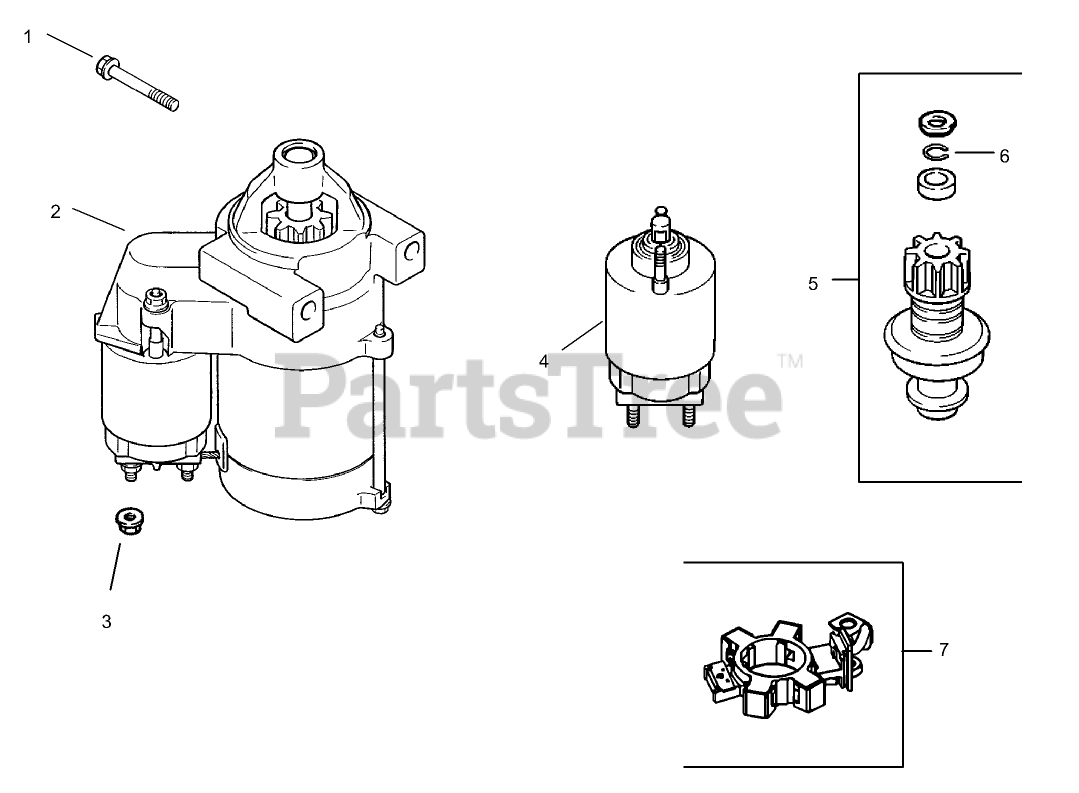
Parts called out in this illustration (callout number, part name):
1	SCREW-FLG (M8X1.25X80)
2	Starter, solenoid (Includes 4-7)
3	NUT-FLANGE (M8X1.25)
4	Solenoid Kit
5	Kit, pinion drive (Includes 6)
6	RING-RETAINING
7	BRUSH HOLDER KIT
